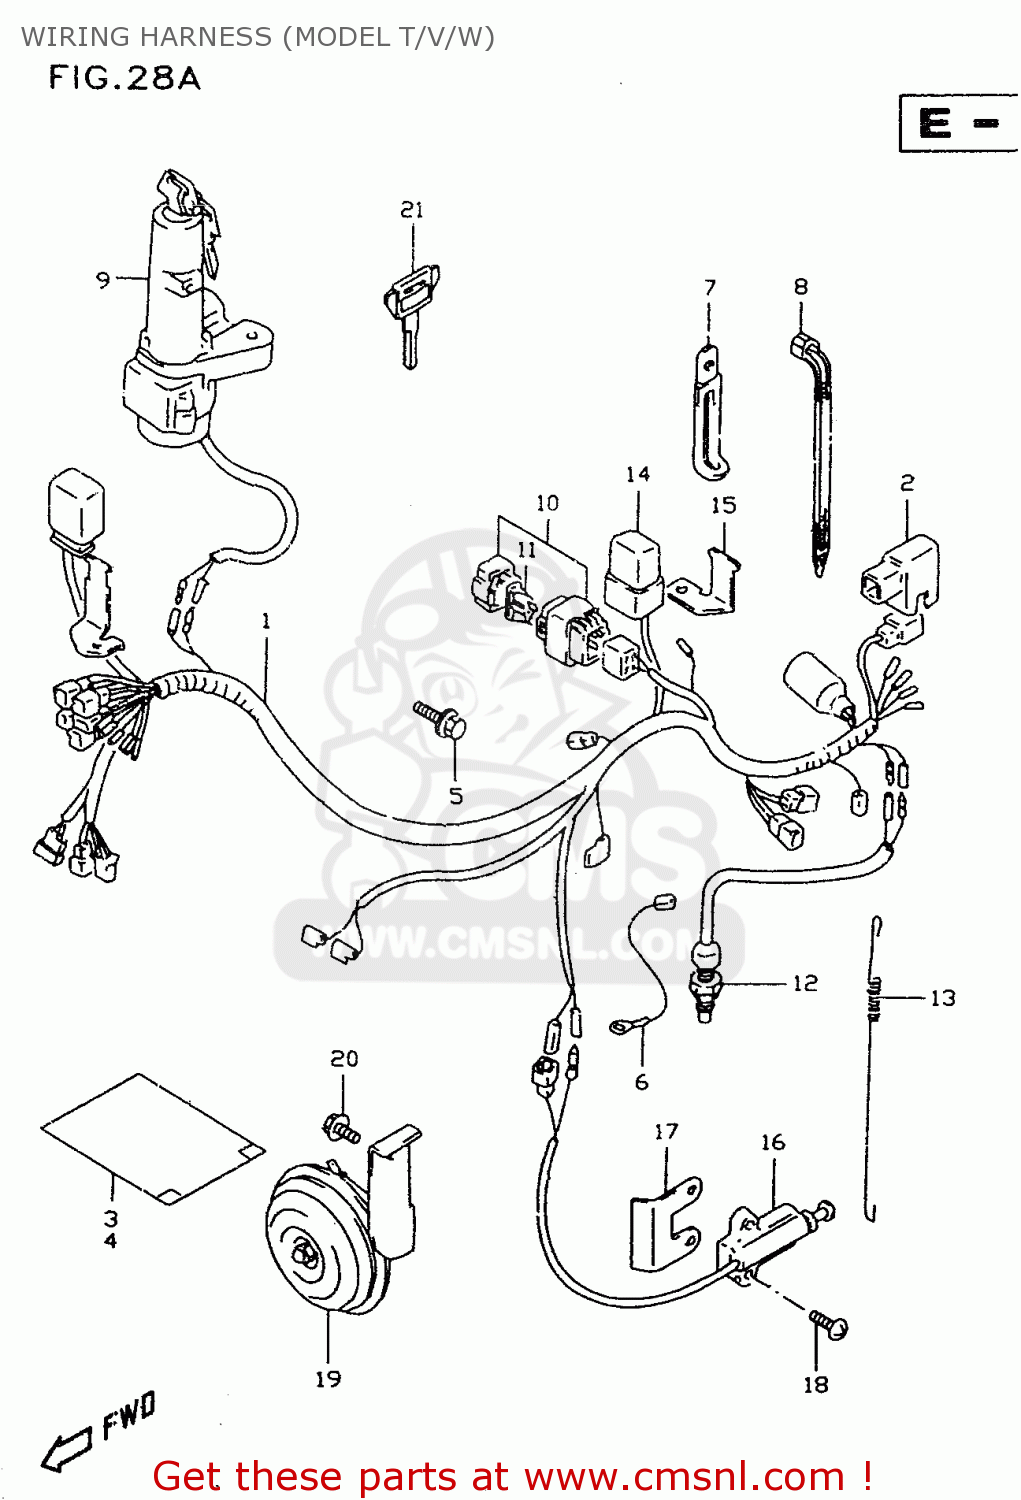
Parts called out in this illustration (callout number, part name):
1	HARNESS,WIRING
2	CAP,BATTERY PLUS
3	GUIDE,WIRING HARNESS
4	COVER,WIRING HARNESS
5	BOLT
6	WIRE,REGULATOR EARTH LEAD
7	CLAMP(L:80)
8	CLAMP(L:33)
9	SWITCH ASSY,IGNITION
10	BOX ASSY,FUSE
11	FUSE(20A)
12	SWITCH ASSY,STOP LAMP
13	SPRING
14	RELAY ASSY
15	BRACKET,FUSE
16	SWITCH ASSY,SIDE STAND WARNING
17	PROTECTOR,SIDE STAND SWITCH
18	SCREW
19	HORN ASSY
20	BOLT
21	KEY,BLANK(TYPE:C)
